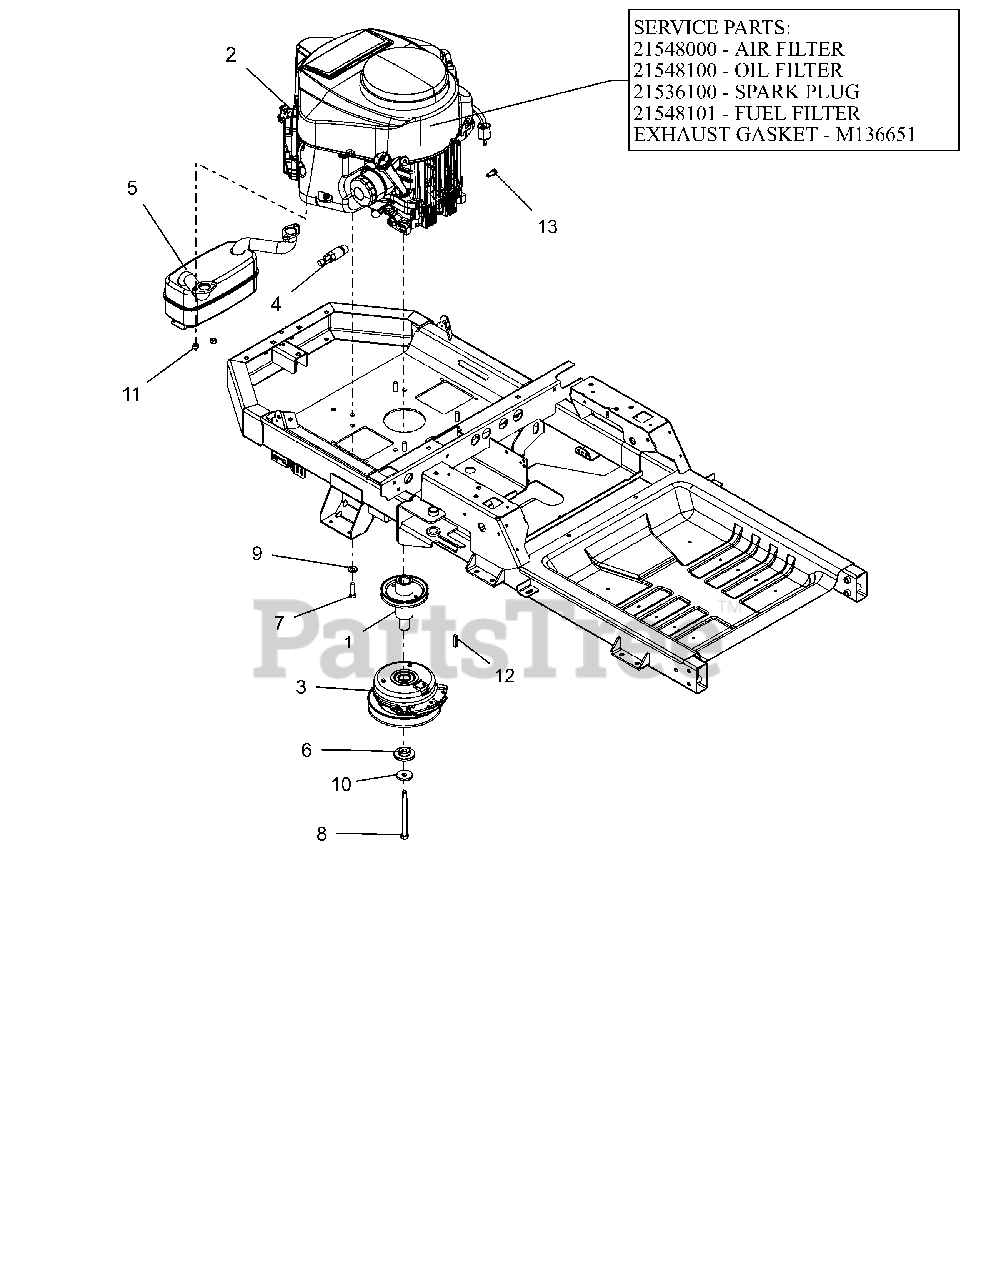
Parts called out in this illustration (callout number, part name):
1	WLDMT, DRIVE SHEAVE (LG XL)CZC
2	ENGINE, KAWASAKI FR730 24HP
2	AIR FILTER, KAWASAKI FR
2	OIL FILTER, KAWASAKI FR
2	PLUG, SPARK
2	FUEL FILTER-KAWASAKI FR
2	GASKET, MUFFLER #
3	CLUTCH,105FTLB MONOPOLE 6.83"
4	DRAIN, OIL M20X2.5
5	MUFFLER, KAWASAKI
6	BSHG-FLG .469X1.06X.574X2.0
7	BLT-HEX.38-16X1.25 G5YZ NYTORQ
8	BLT-HEX.438-20X5 GR8 YZ NYTORQ
9	WASHER, 3/8" SPRING DISC
10	WASHER, 7/16" SPRING DISK
11	NUT-LK-TOP M8-1.25 YWZC
12	KEY-SQ .25 X 1.25 X .25 SAE
13	BLT, HEX M8-1.25X20 G8.8 ZCC
